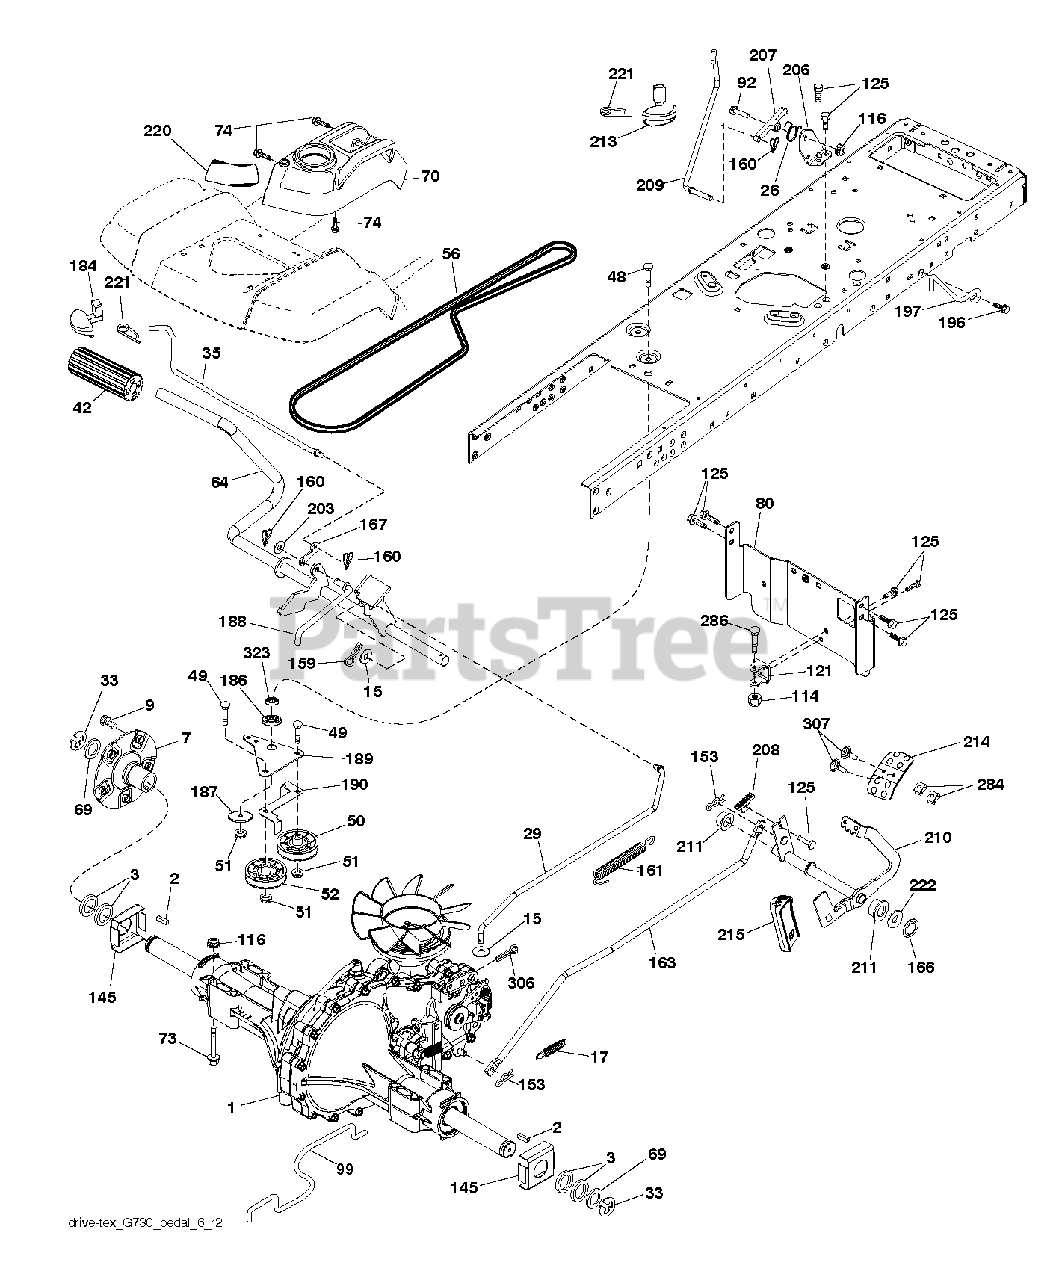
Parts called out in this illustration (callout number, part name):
2	KEY 1/4 X 2.5
7	HUB.ASM.WHEEL.REAR.23"TEX
15	WASHER
17	SPRING.BRAKE.HG3000/3500
26	SPRING.RETURN.CRUISE
33	E RING HYT
35	ROD .BRAKE. PARKING. GT. HUSQ.
42	PEDAL COVER T
48	BOLT.3/8-16X1.50
50	IDLER.FLAT.910.OFFSET
51	NUT LOCK FLG 3/8-16 UNC
52	IDLER.V-GROOVE.910.OFFSET
56	V-BELT.GROUND.DRIVE.
64	SHAFT.ASM.PEDAL.BRK.CNTR
70	CONSOLE.ASM.RH.GT.FC.HUSQ
73	BOLT HEX FLGHD 5/16-18X3 GR. 5
74	SCREW.HI-LO.CONSOLE
80	STRAP.TORQUE.YT.G700
92	BOLT
99	SPRING.BYPASS.YT.G700
114	NUT.71038.31-18.HEX.NYLOCK
116	NUT LOCK HEX FLANGE 5/16-18
121	BRACKET STRAP TORQUE
125	SCREW
145	WASHER.AXLE.FLANGE.HG-3000
153	RETAINER M
159	COTTER PIN
160	RETAINER CLIP
161	SPRING, RETURN LT
163	ROD PEDAL CONTROL
166	NUT.PUSH.625
167	LATCH.BRAKE.SPRING
184	HANDLE.PARKING.BRAKE.H (BLK)
186	SPACER.RETAINER
187	WASHER 12/32X2X10GA
188	RP LINK.CLUTCH.GROUND.DRIVE
189	BELLCRANK.GROUND.DRIVE.TRAPPED
190	KEEPER BELLCRANK ROUND DRIVE
196	SCREW 3/8-16X1
197	BRKT.ANIT-ROTATION.CLUTCH
203	WASHER
206	BRACKET.MOUNT.CRUISE.LATCH
207	LATCH.CONTROL.CRUISE.TEX
208	GEAR.SECTOR.CONTROL.CR
209	ROD.CONTROL.CRUISE.GT.
210	ROCKER.ASM.PEDAL.CONTR
211	BEARING.NYLON
213	KNOB.CONTROL.CRUSIE.HU
214	PEDAL.FORWARD.HUSQVARNA.DEALER
215	PEDAL.REVERSE.TEX.GT.4
220	REFLECTOR.RH.TEX GT
221	RETAINER.SPRING.CLIP.H
222	WASHER 21/32 X 1-1/4 X 10 GA.
284	NUT.U-CHNL.1/4-20.550DP.350PNL
286	BOLT.5/16-18X2.5
306	PIN COTTER
307	SCREW.MACHINE.CR.1/4-20
323	SLEEVE.BELLCRANK
